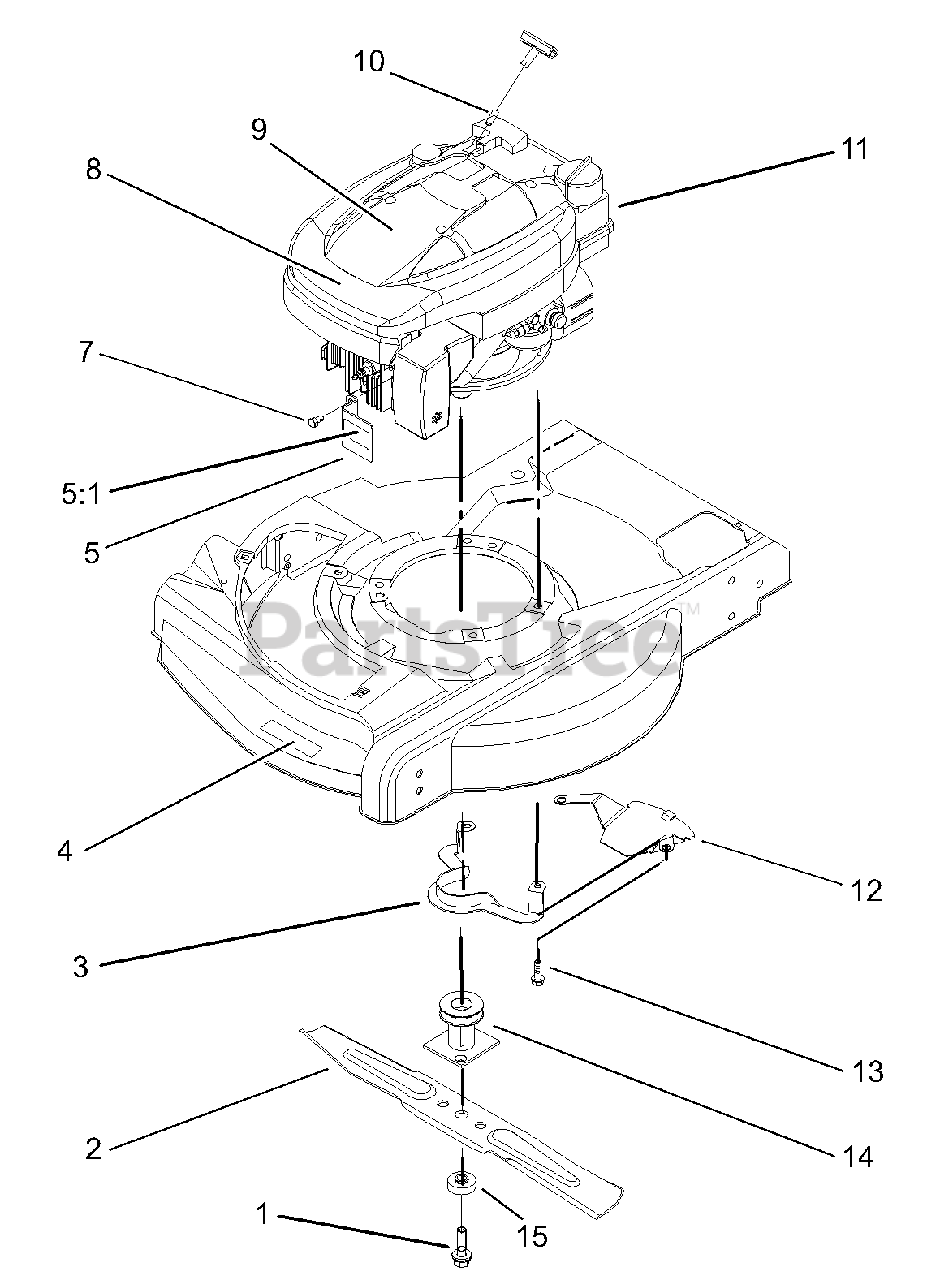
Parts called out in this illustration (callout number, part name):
1	Bolt-Blade,Sems
3	Guide-Belt
4	Decal-Deck
5	Muffler Guard ASM
5:1	Decal-Surface, Hot
7	Screw-HWH
8	Applique
9	Decal-Recoil, Lb
10	Stop-Rope
12	Shield-Grass
13	Screw-Taptite W/Patch
14	Driver-Blade, ASM
